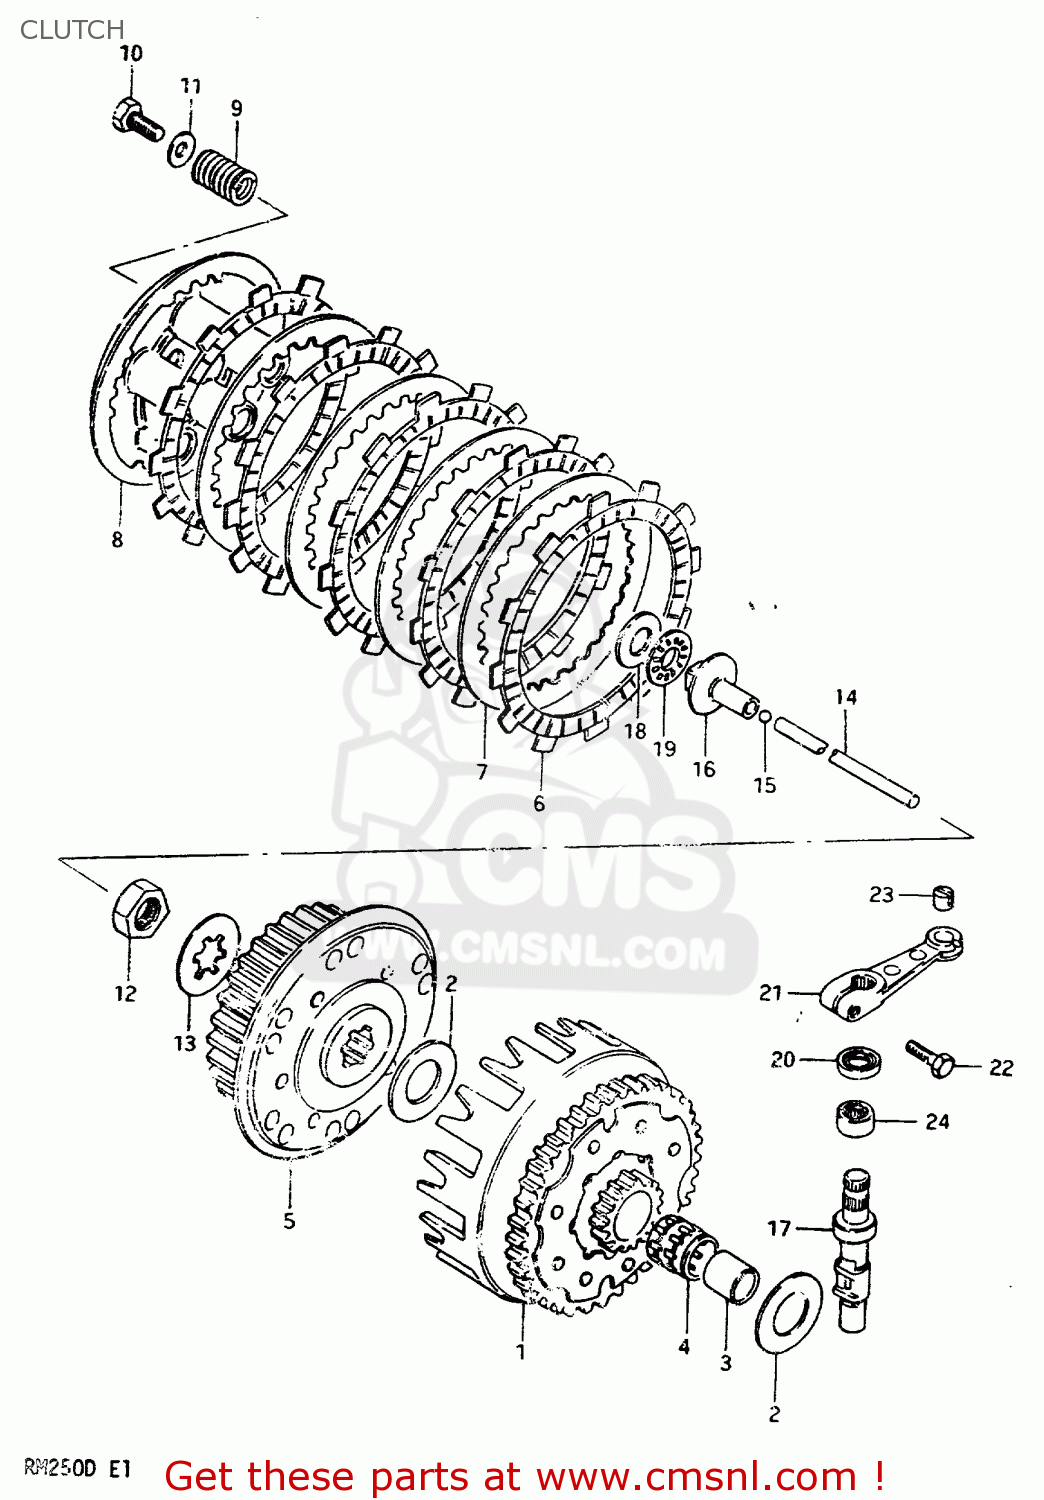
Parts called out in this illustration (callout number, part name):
1	GEAR ASSEMBLY,PRIMARY DRIVE
2	WASHER(20X38X2)
3	SPACER
4	ROLLER BEARING (25X30X2
5	HUB,CLUTCH SLEEVE
6	PLATE,CLUTCH DRIVE (NAS)
7	PLATE,CLUTCH DRIVEN(T:2.0) (NAS)
8	DISC,CLUTCH PRESSURE
9	SPRING
10	BOLT
11	WASHER(6.5X20X1.6)
12	NUT (20MM)
13	WASHER,LOCK
14	ROD,CLUTCH PUSH
15	BALL
16	PIECE,CLUTCH PUSH
17	SHAFT,CLUTCH RELEASE C
18	WASHER(15.5X28X1)
19	BEARING(15X28X2)
20	SEAL,OIL(12X19X5)
21	ARM,CLUTCH RELEASE
22	BOLT
23	PIECE,RELEASE ARM END
24	BEARING(12X19X12)
